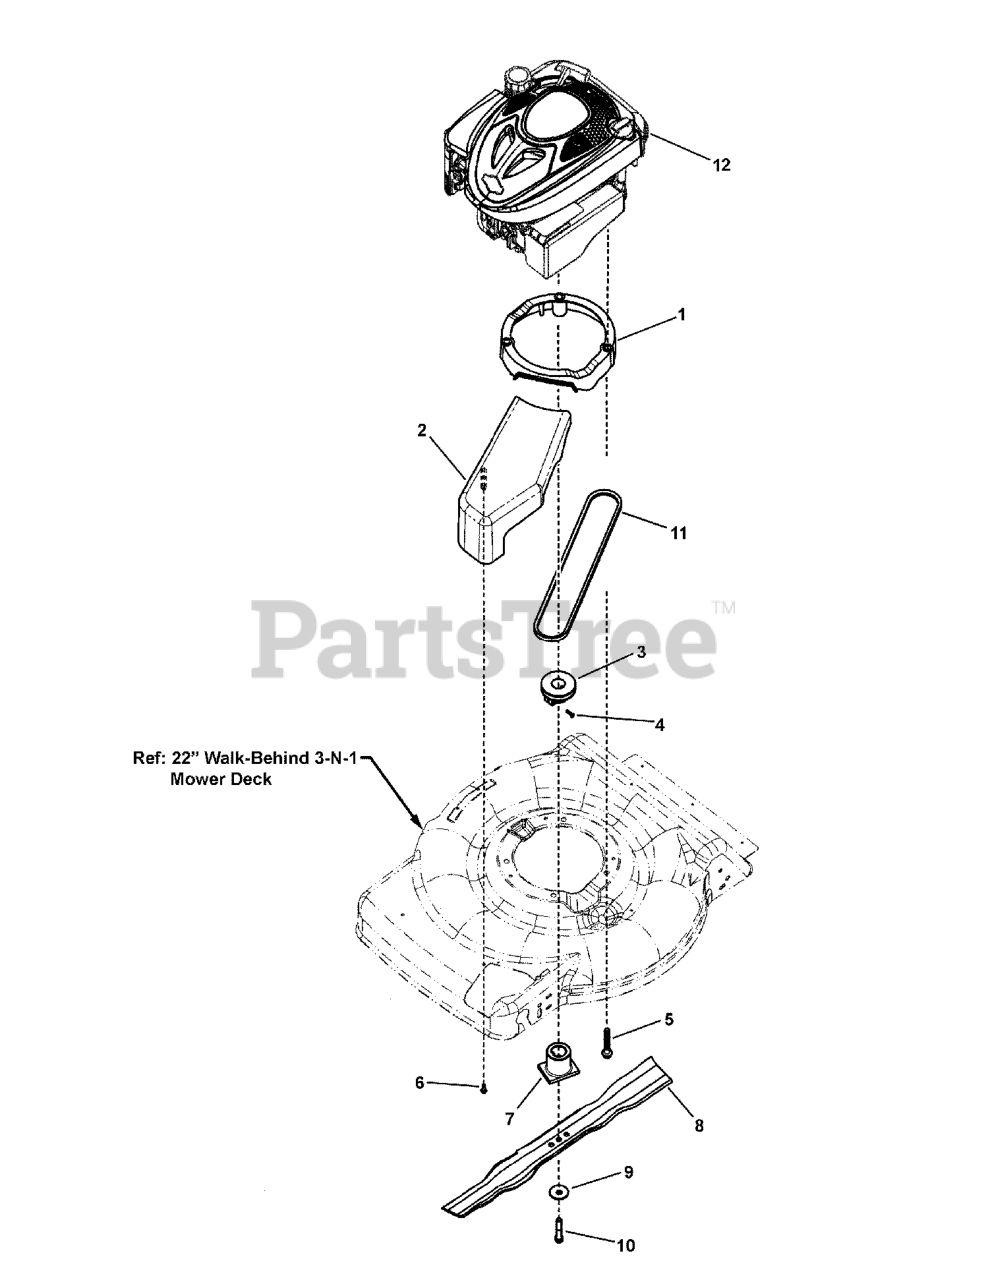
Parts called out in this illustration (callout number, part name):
1	ASSY, Engine Spacer, 22" WBM, Propelled
2	COVER, Belt, Plastic
3	PULLEY, Engine, 22" Deck, SS
4	SCREW, #8-11 Poly Thread x .63, Pan Head Cross Recess
5	BOLT, 3/8-16 NS x 2-1/2" Hex Head
6	SCREW, 4.8MM X 1.59MM X 13MM, Torx Round Washer Head, HI-LO
7	HUB, Blade, 22" Deck
8	BLADE, 22", Walk Mower
9	WASHER, .38" ID x 1.183 OD Bellville
10	BOLT, 3/8-24 NF x 3-1/4" Hex Head, GR 8
11	BELT, Drive 22" WBM, SS
12	* ENGINE, B&S, 650 Ser, X-Spec, B1, Euro
12	* ENGINE, B&S, 675 Series QTM, Euro
